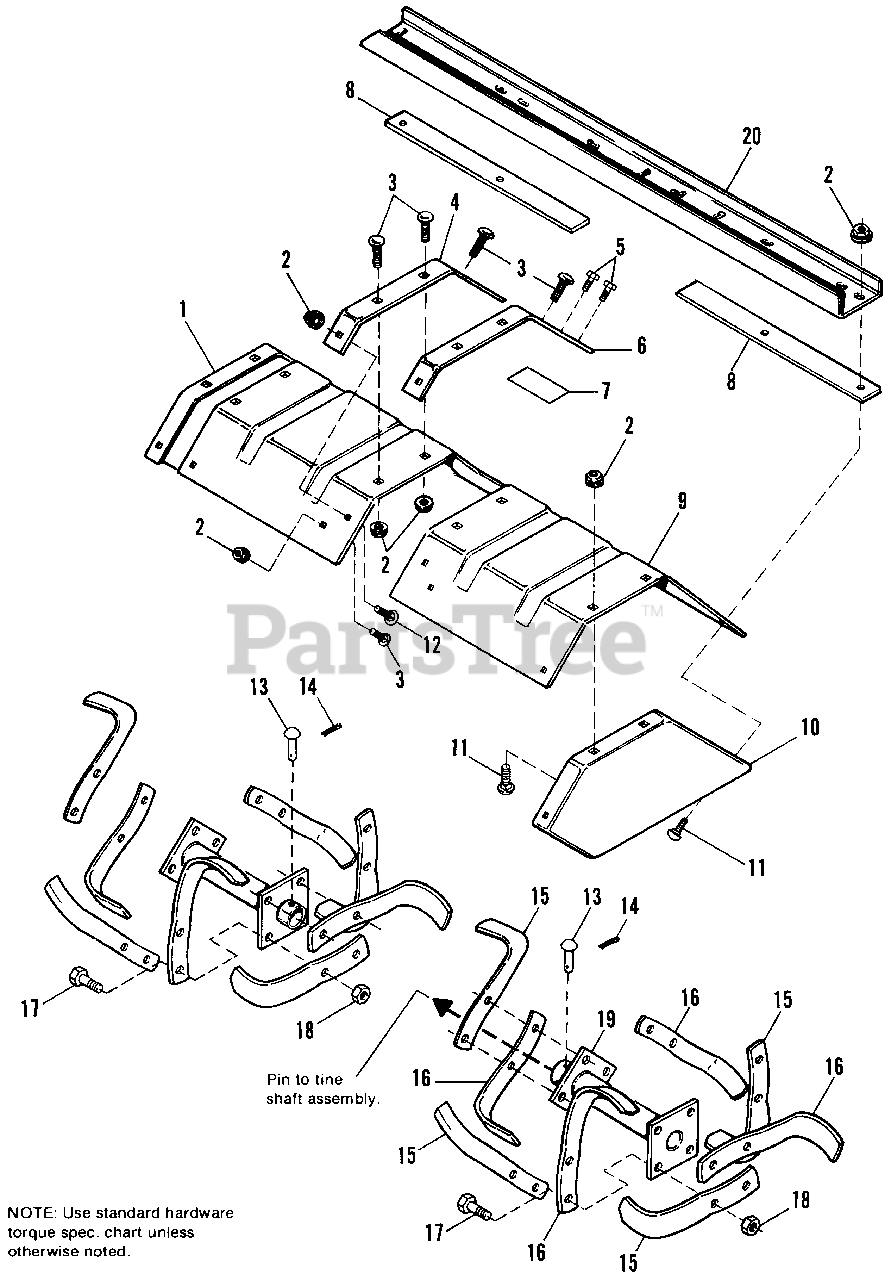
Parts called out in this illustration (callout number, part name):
1	PLATE END, Deflector, R.H.
2	NUT, Hex, Flange, 5/16-18
3	CARRIAGE BOLT, 5/16-18 x 5/8
4	BAR, Reinforcement, R.H.
5	SCREW, Taptite, 5/16-18 x 3/4
6	BAR, Reinforcement, L.H.
7	DECAL, Safety
8	SPACER, Strip
9	DEFLECTOR
10	PLATE END, Deflector, L.H.
11	CARRIAGE BOLT, 5/16-18 x 3/4
12	CARRIAGE BOLT, 5/16-18 x 1
13	PIN
14	PIN, Cotter, 1/8 x 3/4
15	TINE BLADE, L.H.
16	TINE BLADE, R.H.
17	CAPSCREW, Hex, 7/16-20 x 1-1/4
18	LOCKNUT, Hex, 7/16-20
19	HUB & PLATE ASSY., Tine
